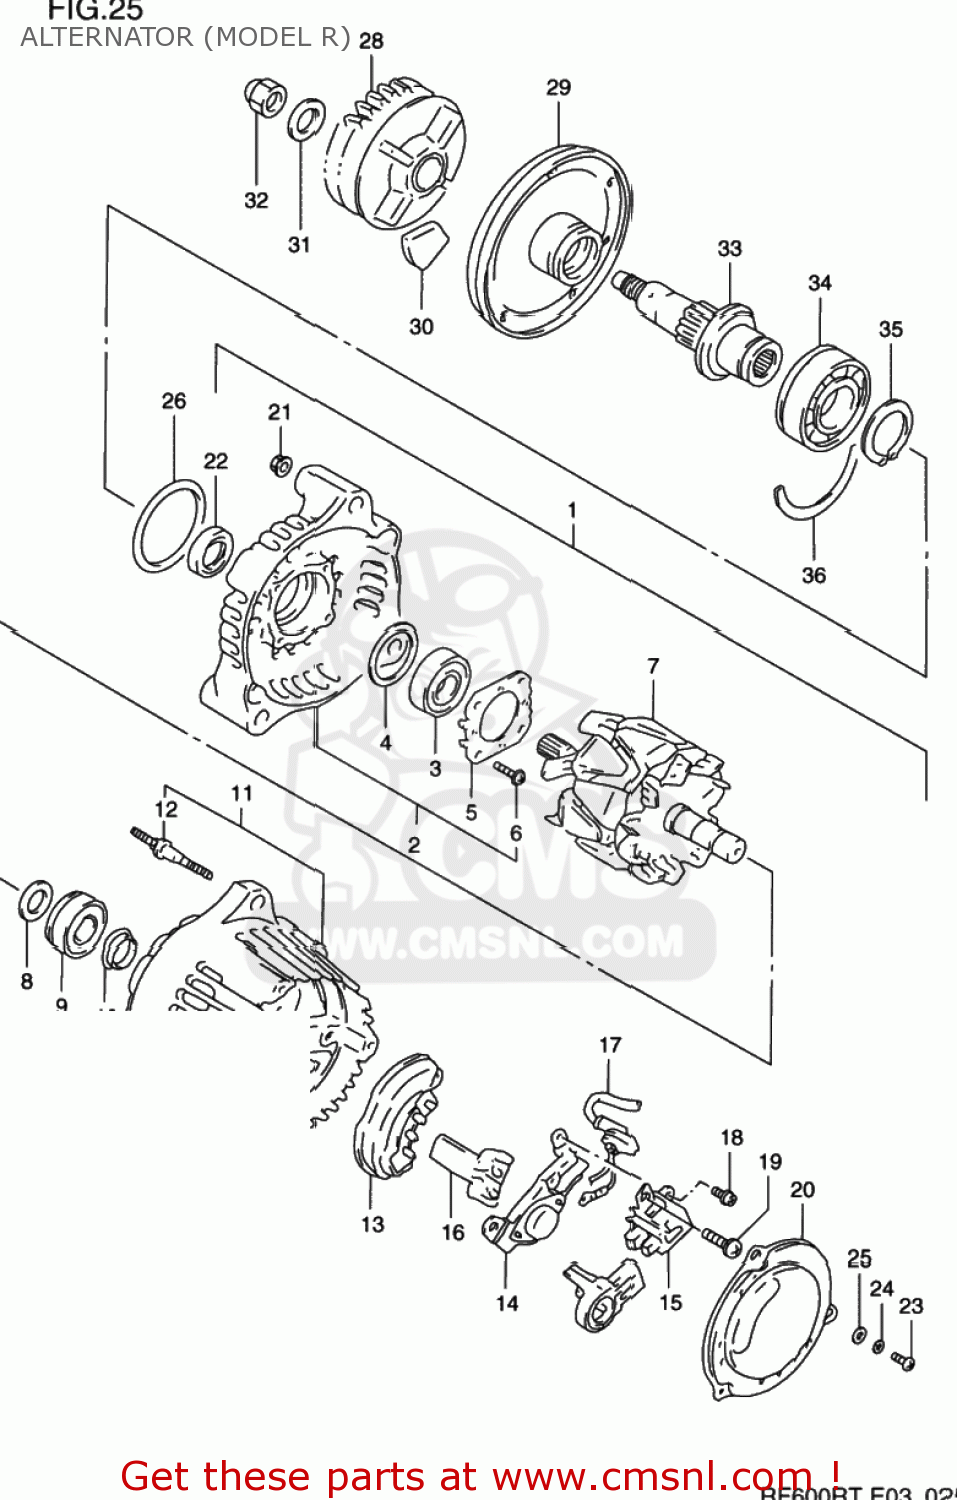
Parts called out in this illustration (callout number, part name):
1	ALTERNATOR ASSEMBLY
2	FRAME,DRIVE END
3	BEARING
4	COVER,BEARING
5	RETAINER,BEARING
6	SCREW,BEARING RETAINER
7	ROTOR ASSEMBLY
8	COVER,BEARING
9	BEARING
10	COVER(2)
11	FRAME,END
12	STUD BOLT
13	HOLDER,RECTIFIER
14	REGULATOR
15	HOLDER,BRUSH
16	COVER,RECTIFIER
17	WIRE,LEAD
18	SCREW 4X6
19	SCREW
20	COVER
21	NUT
22	SEAL SET,OIL
23	SCREW
24	WASHER,LOCK
25	WASHER,5MM
26	O RING
27	BOLT
28	GEAR,GENERATOR DRIVEN
29	HOUSING,GENERATOR DAMPER
30	DAMPER,GENERATOR
31	WASHER
32	NUT
33	SHAFT,GENERATOR DRIVE
34	BEARING(25X52X15)
35	CIRCLIP
36	C RING
